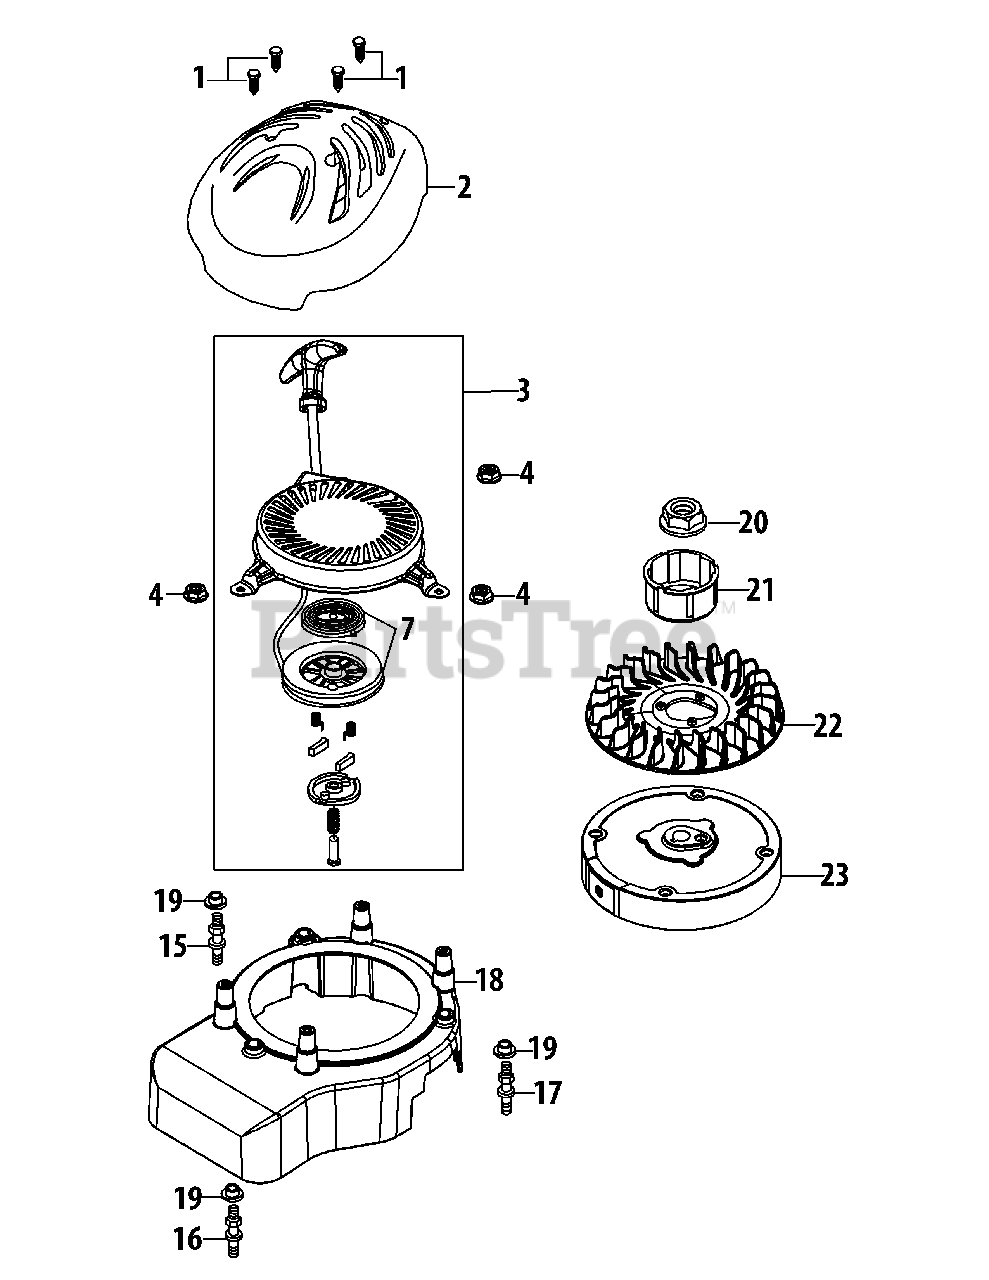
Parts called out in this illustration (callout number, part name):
1	Self-Tapping Bolt, #12-16 X 1.00"
2	Outer Shroud
3	Recoil Starter Assembly
4	Nut M6X10Mm Starter/Carb/Muff
7	Recoil Spring And Pulley Assy
15	Shroud Stud Left/Black/Wh Zinc
16	Shroud Stud Front/Unmarked/Wh Zinc
17	Shroud Stud Right/White/Wh Zinc
18	Inner Shroud
20	Flywheel Nut M14
21	Starter Cup
22	Cooling Fan
